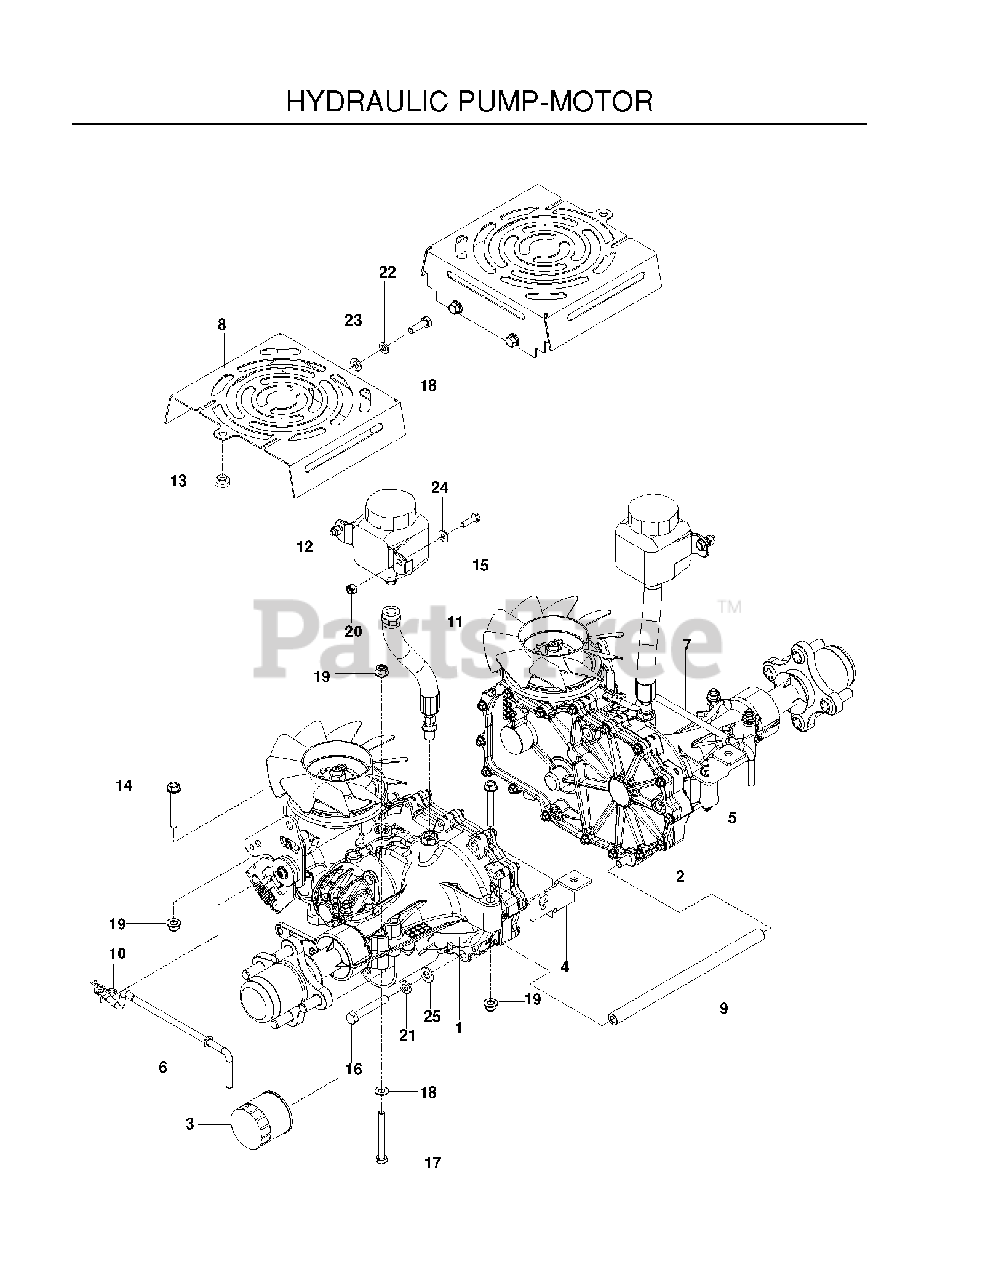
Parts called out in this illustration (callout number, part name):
1	HG_TRANS ZT-3100 LT
2	HG_TRANS ZT-3100 RT
3	HG_FILTER, ZT4800 52114
4	BRACKET.TRANS.LT.BLACK
5	BRACKET, TRANS, RT BLACK
6	LINKAGE, LEFT BYPASS
7	LINKAGE, RIGHT BYPASS
8	SHIELD, FAN, BLK
9	TUBE, SPACER, 3400
10	HAIRPIN #2
11	HOSE ASSY, EXPANSION
12	TANK.EXPANSION.350ML 71328
13	GROMMET, BUMPER
14	HHFS 5/16-18 X 2.25 GD 5
15	HCS 1/4-20X7/8 GR5
16	HCS 3/8-16X2-1/4 LOC PATCH GR8
17	HCS 5/16C X 2-3/4
18	HCS 5/16C X 1
19	5/16-18 NYLOC FLANGE NUT
20	RP_NUT 1/4-20 NYLOC
21	SLW 3/8 STD
22	WASHER 5/16 LOCK
23	FLAT WASHER 5/16 SAE
24	WASHER 1/4 SAE
25	WASHER 3/8 SAE FLAT
